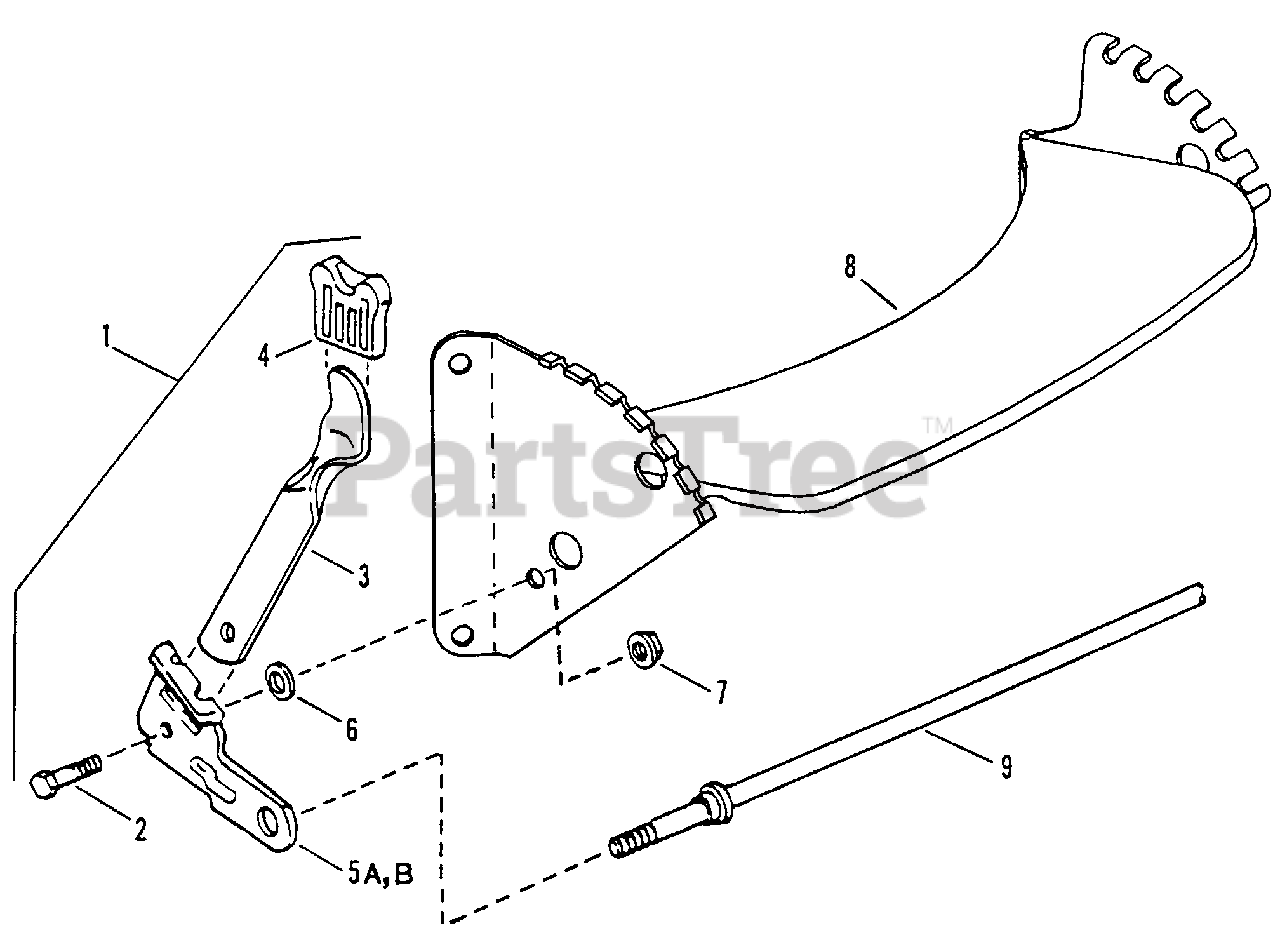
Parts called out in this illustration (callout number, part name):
1	ASSEMBLY, Arm Left Wheel
2	BOLT, 5/16-18 x 3/4" Shoulder
3	LATCH, Height
4	GRIP, Latch
5A	ARM, Left Wheel
5B	ARM, Right Wheel
6	RETAINER, 5/16 Bolt
7	NUT, 5/16-18 Hex Flange Lock, Grade 5
8	BRACKET, Front Wheel
9	AXLE
